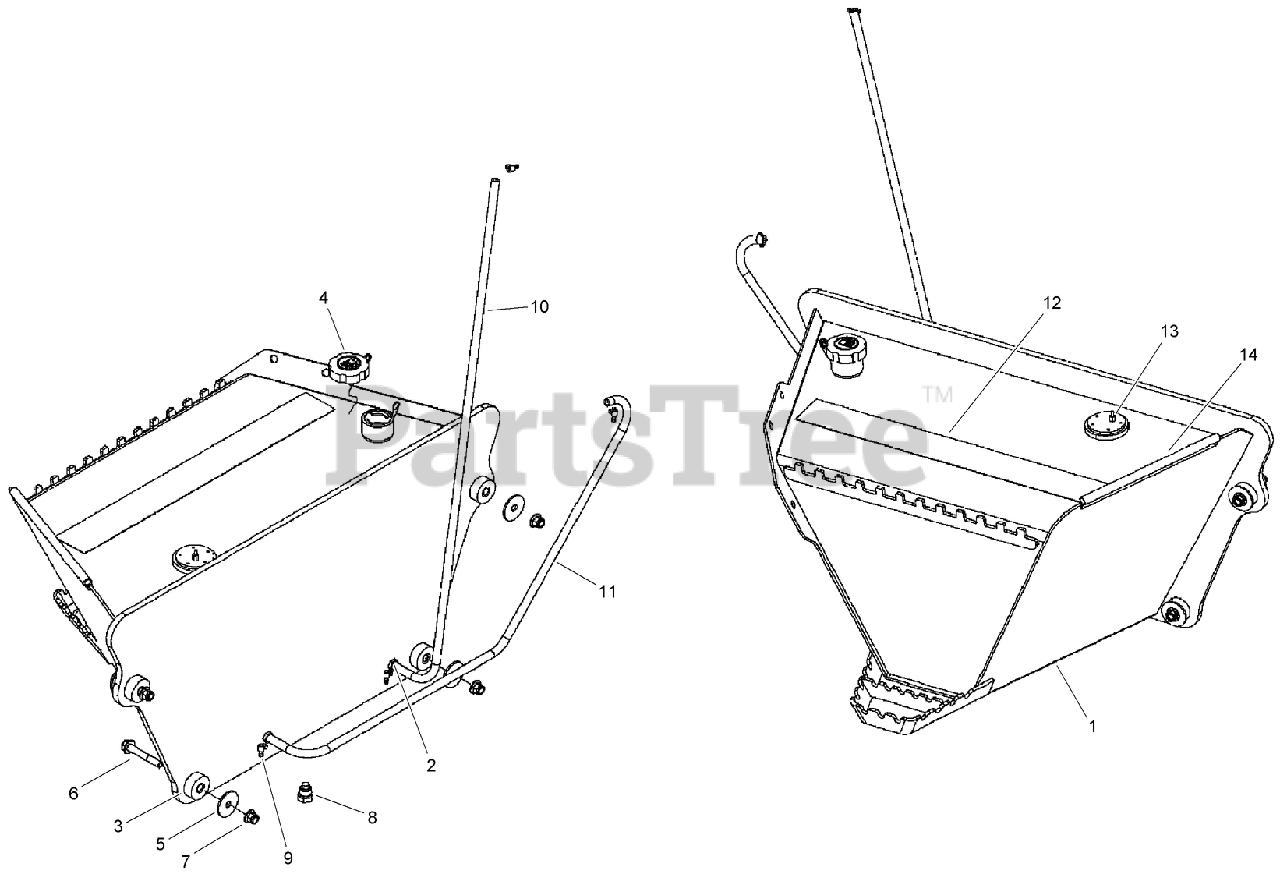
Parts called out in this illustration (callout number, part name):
1	WELDMENT-Fuel Tank
2	FITTING-STRAIGHT
3	ISOLATOR-MOUNTING, UNIVERSAL
4	CAP-DIESEL FUEL W/ LOCK
5	WASHER-FLAT
6	SCREW-HHF
7	NUT-HHF, LOCK
8	PLUG-HEX, MAGNETIC
9	CLAMP-Hose Type M #04
10	HOSE-Fuel Tank
11	HOSE-Fuel Tank
12	STRIP-ANTI SKID
13	SENDER-FUEL LEVEL
14	SEAL-Hood
